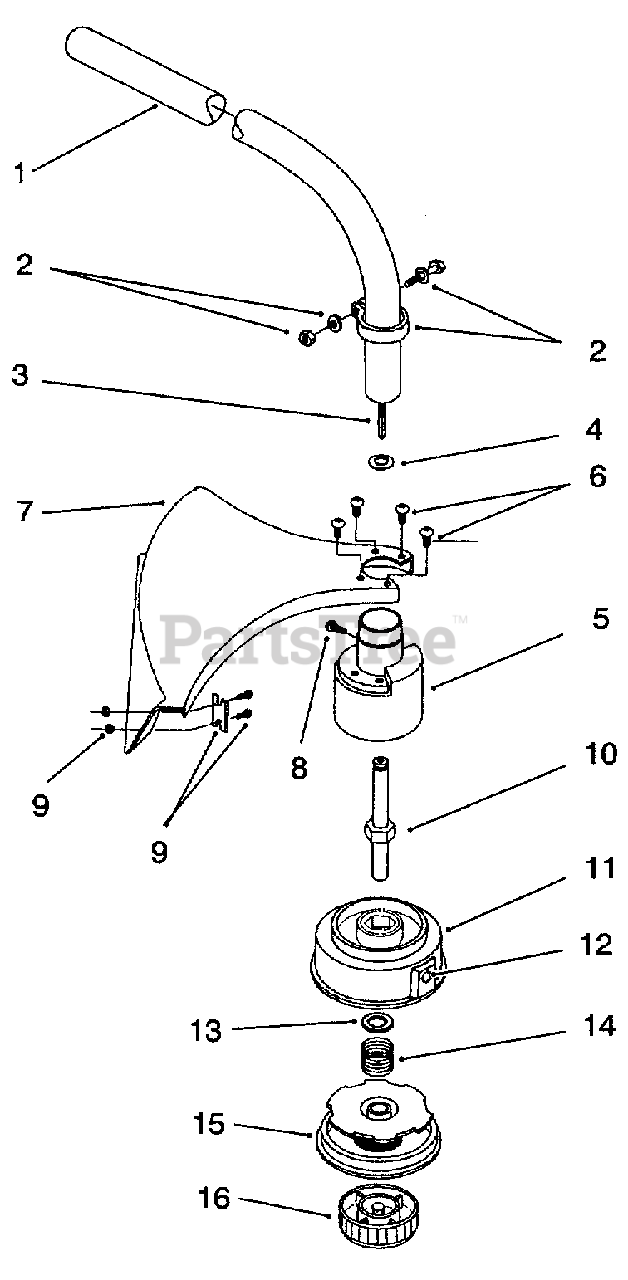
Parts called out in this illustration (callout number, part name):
1	Drive Shaft Housing Asm.
2	Lower Clamp Assembly
3	Lower Flexible Drive Shaft
5	Bushing Housing Assembly
6	Guard Mounting Screw Asm.
7	Guard and Blade Assembly (Incl. Ref. # 9)
8	Anti-Rotation Screw
9	Blade Assembly
10	Spool Shaft
11	Outer Spool and Eyelet Asm. (Incl. Ref. #12)
13	Retainer
15	Inner Reel
16	Bump Head Knob Assembly
